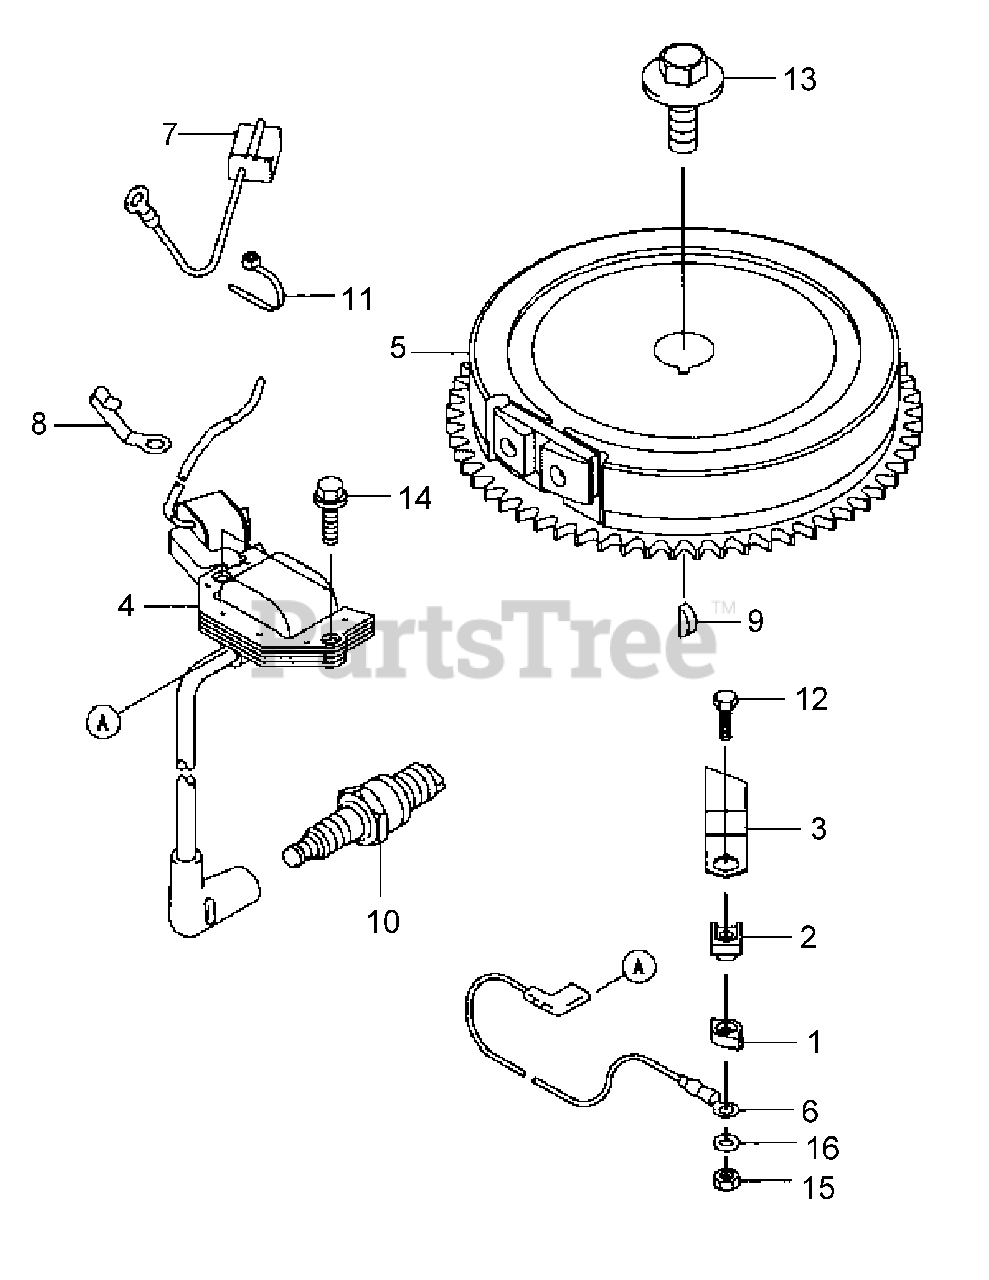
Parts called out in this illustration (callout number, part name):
4	Ignition Coil Assy.
10	Spark Plug
14	Flanged Bolt
15	Hex Nut
16	Plain Washer
